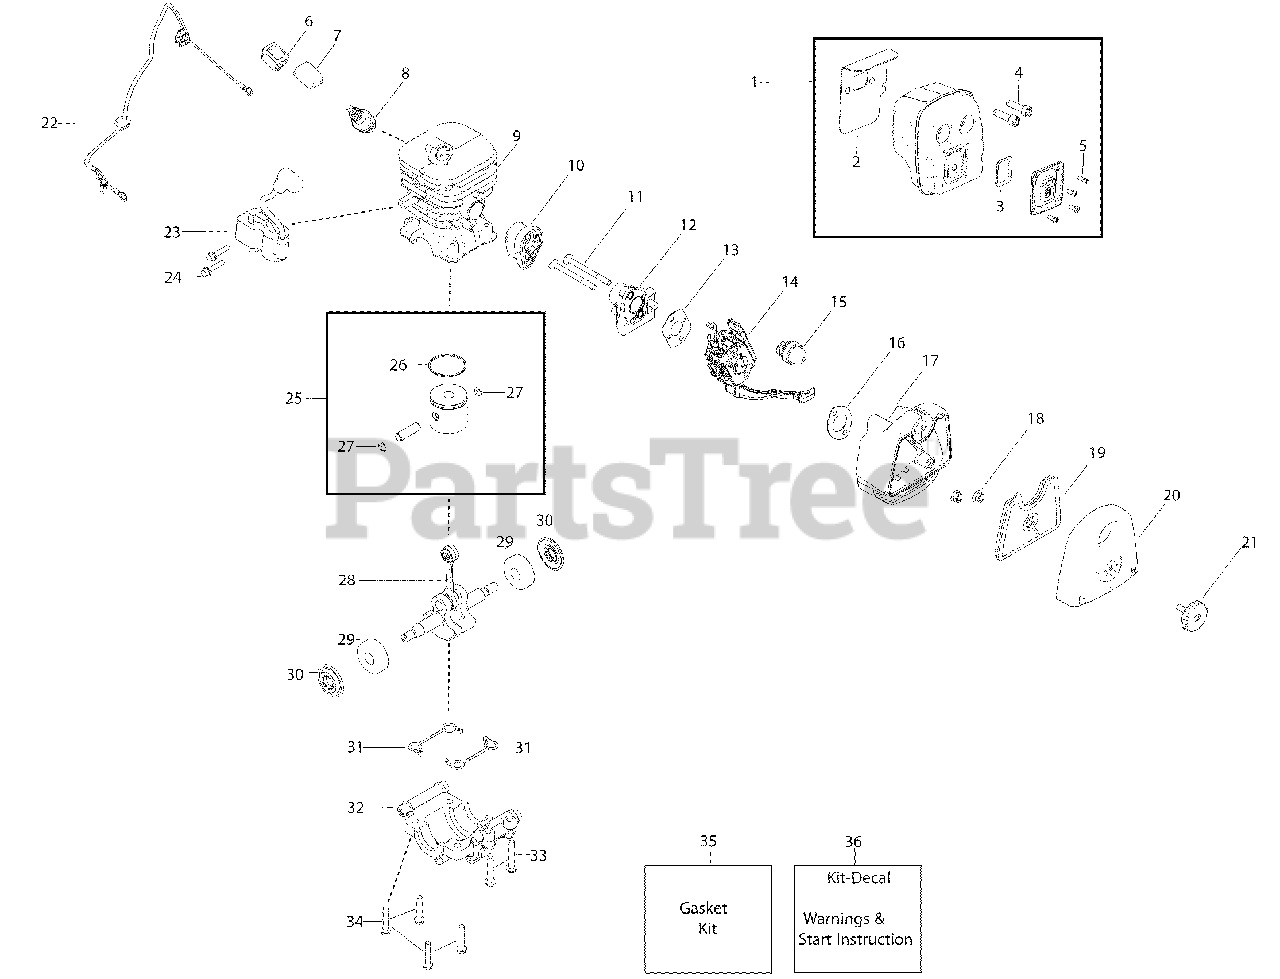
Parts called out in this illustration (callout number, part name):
1	Assy - Muffler
2	Gasket - Muffler
3	Kit - Spark Screen
4	Bolt - Muffler
5	Screw
7	Protector - Switch
8	Accy - Spark Plug
9	Cylinder - Chrome
10	Boot - Carb.
12	Plate - Carb.
13	Gasket - Carb.
14	Kit - Carb.
15	Bulb - Purge
16	Gasket - Airbox
17	Base - Airbox
18	Nut - Carb screw
19	Filter - Air
20	Cover - Airbox
21	Assy - Airbox Knob
22	Assy - Leadwire
23	Module - Ignition
25	Kit - Piston
26	Ring - Piston
27	Retainer - Piston pin
28	Kit - Crankshaft
30	Kit - Crankshaft seal
31	Seal - Cylinder
32	Cap - Bearing
35	Kit - Gasket
36	Kit - Decal
